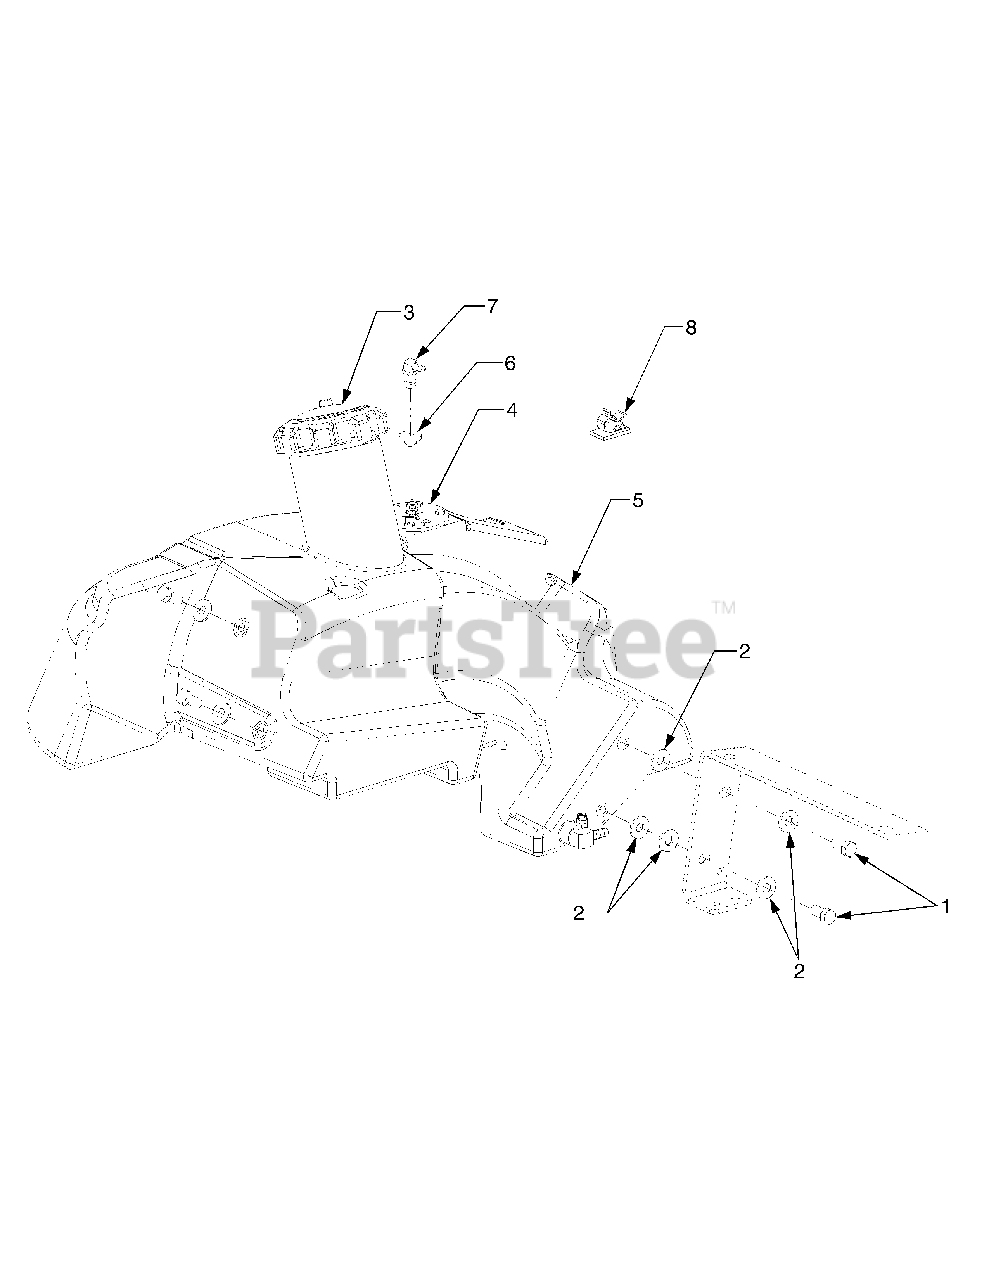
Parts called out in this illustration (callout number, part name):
1	Screw, Hex Cap, Lock 3/8-16 x .75 GR5
2	Washer, Flat, .385 x .87 x .092
3	Cap, Fuel
4	Sensor, Fuel Level
5	Tank, Fuel
6	Bushing, Rubber
7	Fitting, Fuel Return
8	Clip, Retainer
